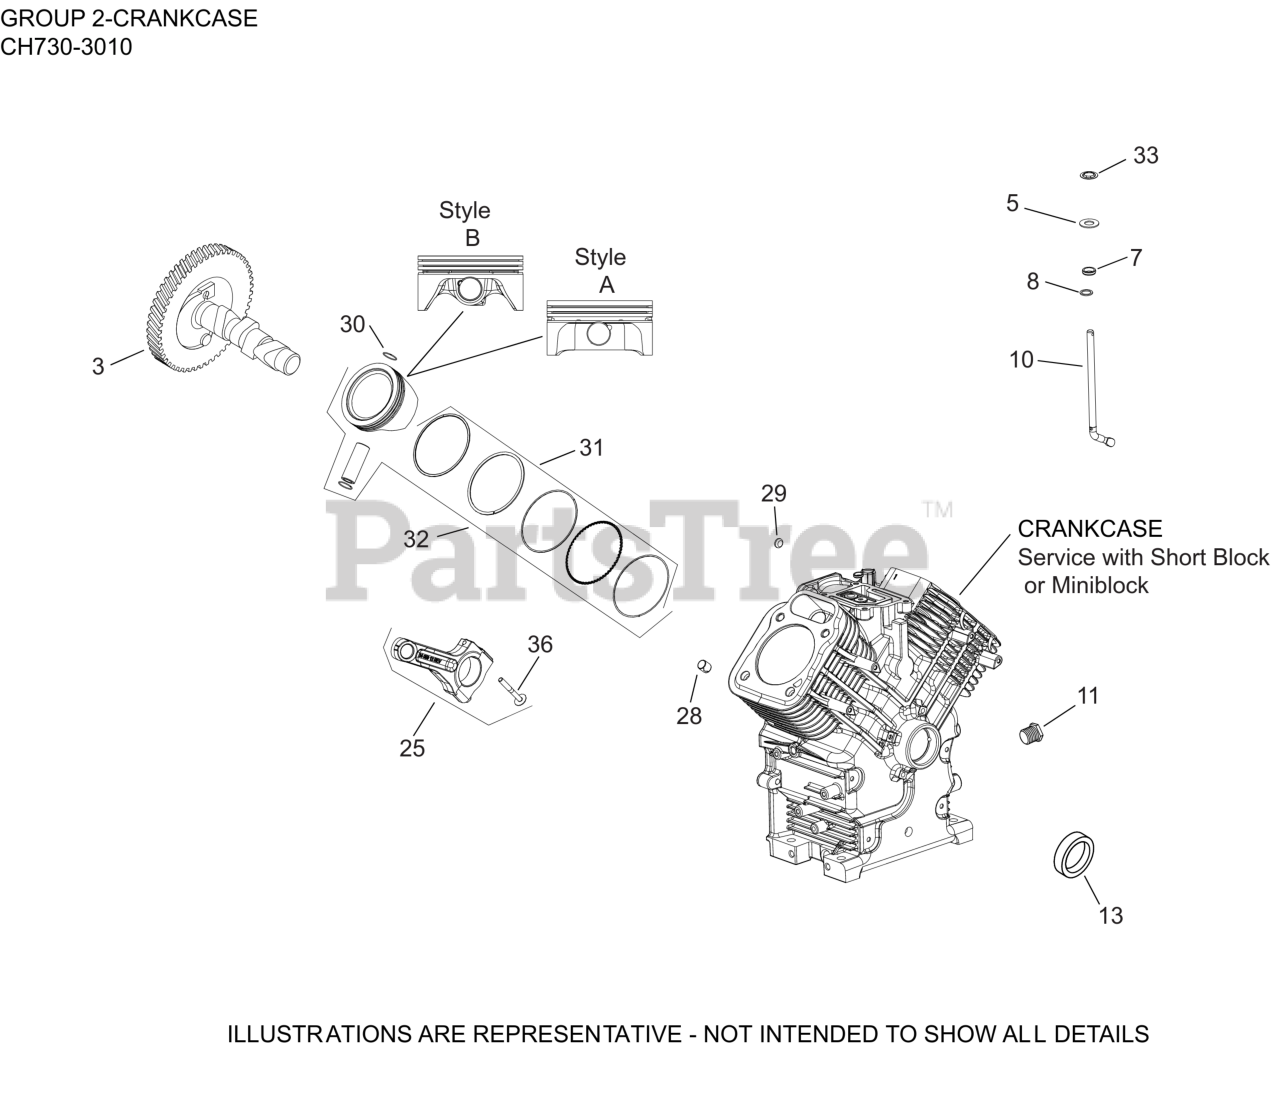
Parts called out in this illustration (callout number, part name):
3	KIT, CAMSHAFT-(#2401225S)
5	WASHER, FLAT 9 MM
7	SEAL, GOVERNOR CROSS SHAFT
8	WASHER, FLAT 11/32"
10	SHAFT, GOVERNOR CROSS
11	PLUG, HD PIPE 3/8"
13	SEAL, OIL (HELIX LIP)
25	ROD, ASSEMBLY CONNECTING
28	PIN, LOCATING
29	PLUG, CUP
30	RETAINER, PISTON PIN
31	RING SET(STD)STYLE B-1.2mm Tp RING THICK
31	RING SET(.08)STYLE B-1.2mm RING THICK
31	RING SET(.25)STYLE B-1.2mm Tp RING THICK
31	RING SET(.50)STYLE B-1.2mm Tp RING THICK
32	KIT, PISTON 725CC (STD) STYLE B
32	KIT, PISTON 725CC (.08) STYLE B
32	KIT, PISTON 725CC (.25) STYLE B
32	KIT, PISTON 725CC (.50) STYLE B
33	RETAINER, RING
36	KIT, ROD BOLTS-(#25086677S)
